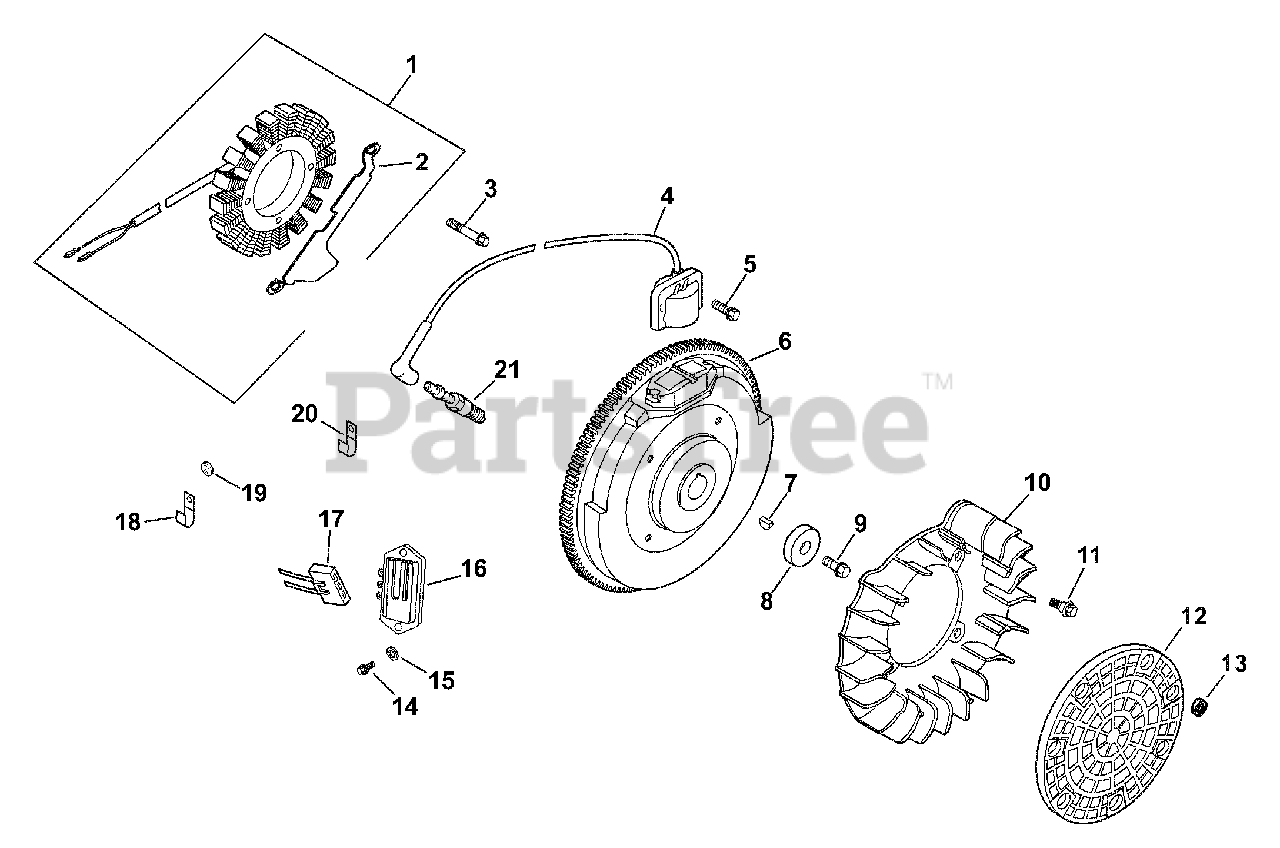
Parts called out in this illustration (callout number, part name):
1	Kit, 15 amp stator (Includes 2)
2	Bracket, stator wire
3	Screw, hex. cap M5x0.8x25
4	Module, ignition
5	Screw, hex. flange M5x0.8x20
6	Flywheel
8	Washer, plain 3/8"
9	Screw, hex. flange M10x1.5x46
10	Fan
11	Bolt, shoulder
12	Screen, grass
13	Retainer, grass screen
14	Screw, phillips hd. 11-16x7/8"
15	Washer, plain 3/16"
16	Rectifier-regulator 15 amp
17	Connector (3 contact)
18	Clip, cable
19	Washer, plain 1/4"
21	Spark Plug
